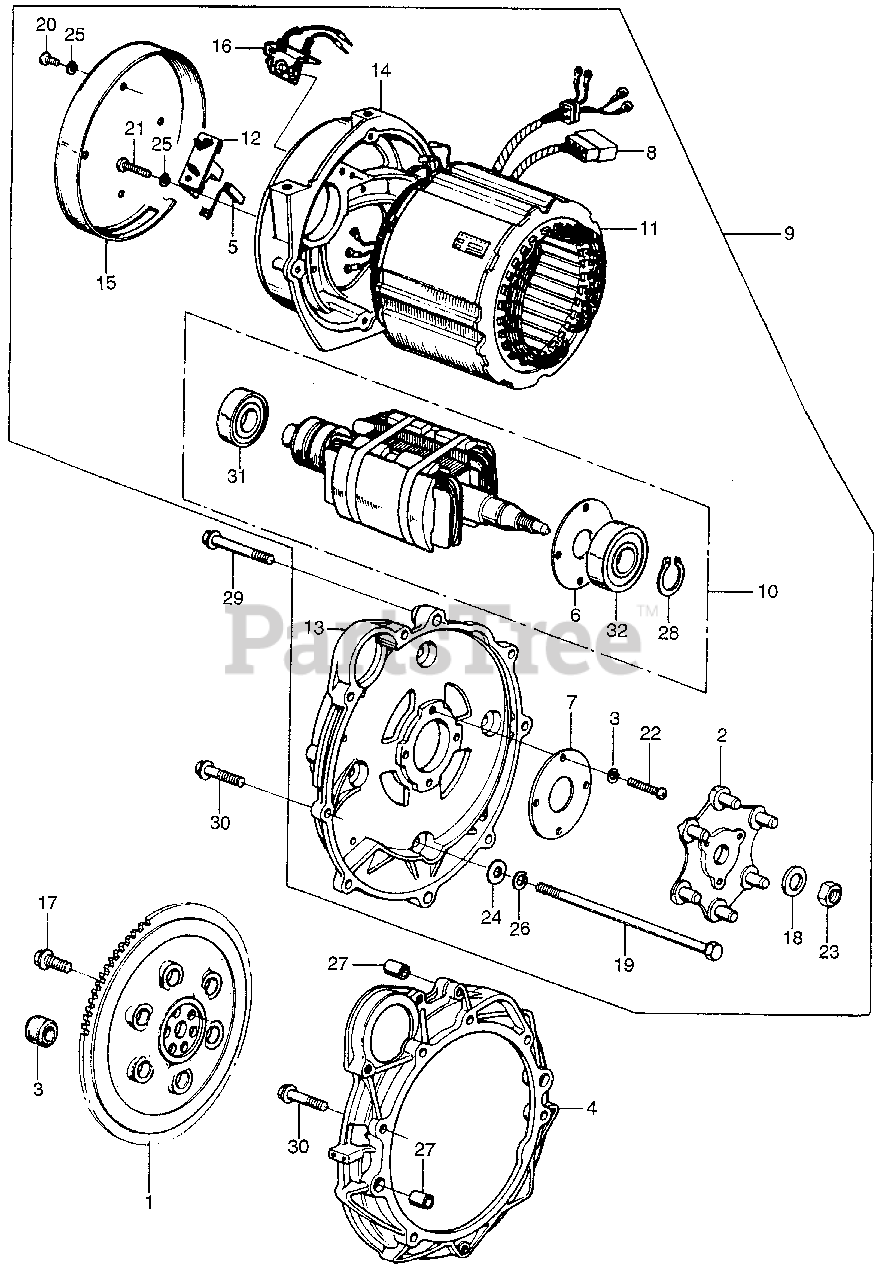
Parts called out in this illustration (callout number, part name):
2	PIN, FLANGE
3	RUBBER, COUPLING (NOT AVAILABLE)
4	CASE, COUPLING
5	BRUSH, CARBON (NOT AVAILABLE)
6	COVER B, BEARING
7	COVER A, BEARING
8	CONNECTOR, POLE MALE (8) (NOT AVAILABLE)
9	ALTERNATOR ASSY. *NH83L* (OFF BLACK)
11	STATOR (NOT AVAILABLE)
12	STAY, BRUSH (NOT AVAILABLE)
13	HOUSING, FR. ALTERNATOR
14	HOUSING, RR. ALTERNATOR
15	COVER, RR. *NH83L* (OFF BLACK)
16	DIODE ASSY., D.C.
17	BOLT, HEX. (10MM)
18	WASHER (40MM)
19	BOLT, HEX. (8X200)
20	SCREW, PAN (5X16)
21	SCREW, PAN (5X25) (NOT AVAILABLE)
22	SCREW, PAN (5X28)
23	NUT, HEX. (18MM) (NOT AVAILABLE)
24	WASHER, PLAIN (8MM)
25	WASHER, SPRING (5MM)
26	WASHER, SPRING (8MM)
27	PIN A, DOWEL (14X20)
28	CIRCLIP (OUTER) (30MM)
29	BOLT, FLANGE (8X55)
30	BOLT, FLANGE (8X32)
31	BEARING, RADIAL BALL (6205UU)
32	BEARING, RADIAL BALL (6306UU)
